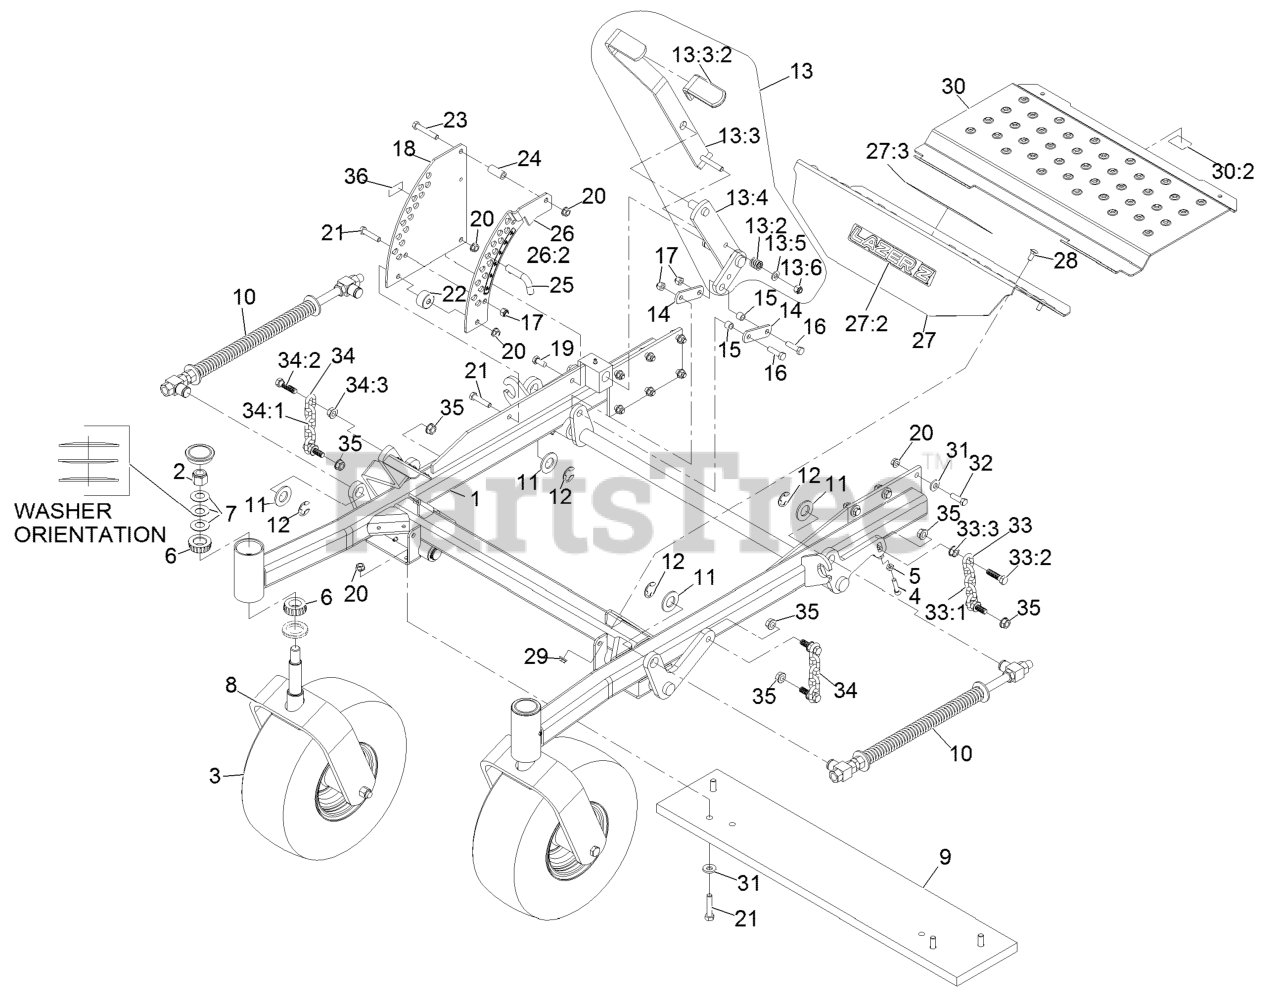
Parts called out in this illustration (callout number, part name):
1	ASM-Frt Frm 60Rd
2	NUT-LOCK, NI
3	ASM-WHL AND TIRE
4	SCREW-HSH
5	NUT-JAM
6	Cone-Bearing Tapered Roller
7	WASHER-BELLVILLE
8	WLD-CASTER FORK 15
9	BAR,WEIGHT 38.1#
10	FRONT FRAME SPRING ASM
11	WASHER-FLAT
12	RING-RETAINING, EXT
13	ASM,Deck Lift Handle
13:2	SPRING-COMPRESSION
13:3	LIFT LEVER/GRIP ASM
13:3:2	GRIP-LEVER, LIFT
13:4	WLD,ARM DECK LIFT
13:5	WASHER-FLAT
13:6	NUT-LOCK, NI
14	ARM-LIFT, DECK
15	BUSHING
16	SCREW-HH
17	NUT-LOCK, NI
18	PLATE-DECK LIFT NOTCHED O
19	SCREW-HH
20	NUT-HHF, WHIZ
21	SCREW-HH
22	Stop, Deck Height
23	SCREW-HH
24	BUSHING-LEVER, LIFT
25	PIN-HOC
26	PLATE-LIFT, DECK W/DECAL
26:2	DECAL-HEIGHT OF CUT
27	ASM, FLOORPAN FRONT W/DEC
27:2	DECAL, LAZER MODEL
27:3	DECAL-DANGER
28	BOLT-CARR
30	ASM, FLOORPAN LIFTOUT W/D
30:2	Decal-Guard
31	WASHER-BELLEVILLE
32	SCREW-HH
33	DECK CHAIN ASM
33:1	CHAIN-LIFT, DECK
33:2	SCREW-HH
34	DECK CHAIN ASM
34:1	CHAIN-LIFT, DECK
34:2	SCREW-HH
36	Decal-Patent Ttco.Com
